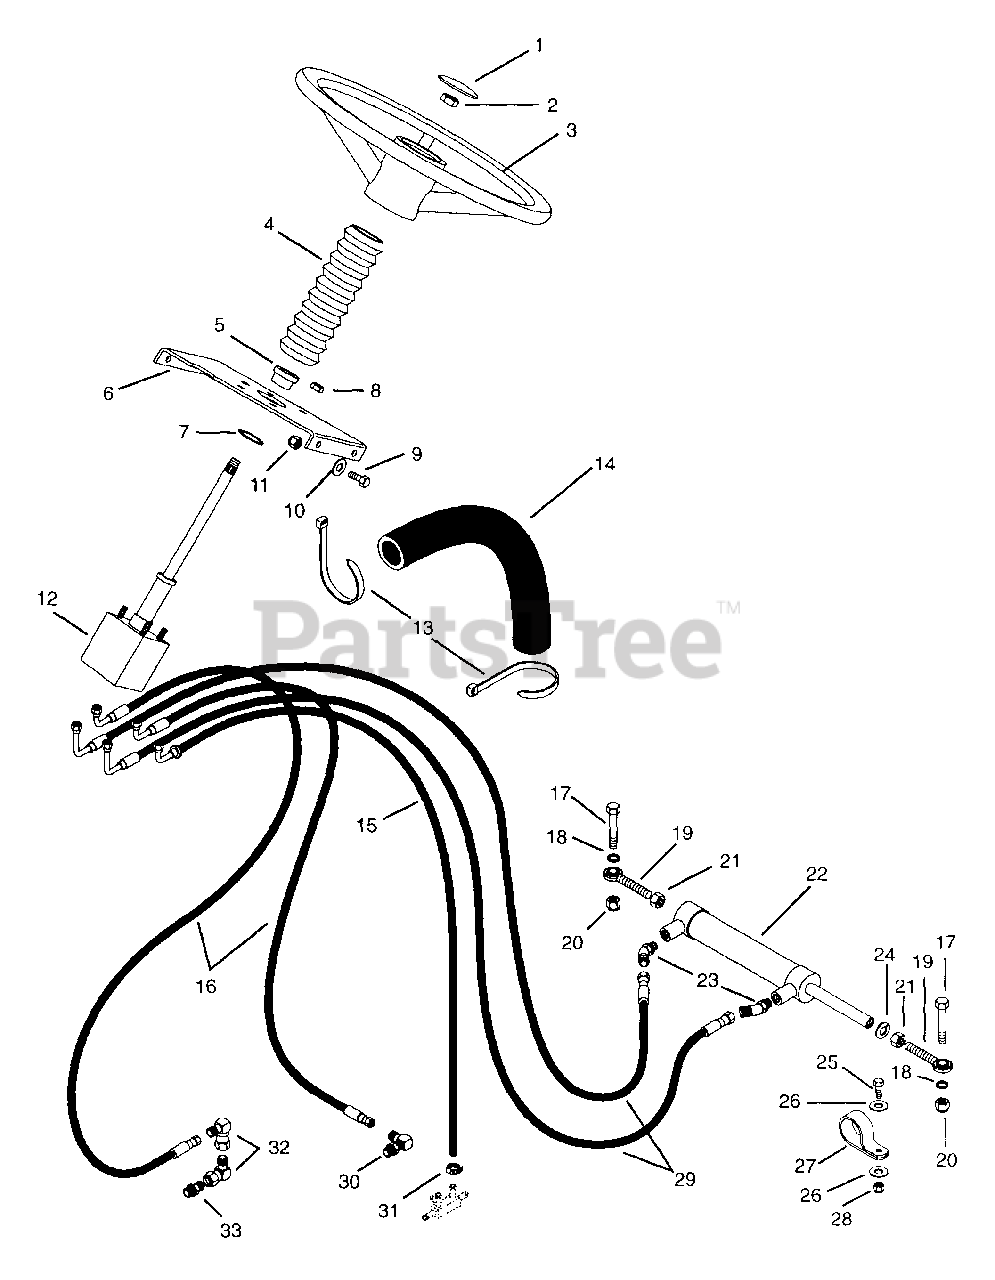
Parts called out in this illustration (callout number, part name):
1	Steering Wheel Cap
2	Nut-Jam .625-11
3	Steering Wheel
4	Steering Column Boot
5	Bushing-Flange .762 x 1.0 x .580 x 1.48
6	Bracket, Steering Pump
7	Ring-Retaining-External 1.31 x .05
8	Nut-Locking-Nylon .312-24 Grade 2
9	Bolt-Hex .31-18 x .75 Grade 5
10	Washer-Flat-Steel .344 x .688 x .065
11	Nut-Locking-Nylon .312-18 Grade 2
12	Power Steering Unit
13	Tie Wrap, Black
14	Sleeve 12"
15	Assembly, Hydraulic Hose
16	Assembly, Hydraulic Hose
17	Bolt-Hex .50-13 x 2.00 Grade 5
18	Bushing
19	Assembly, Rod End (Right Hand)
20	Nut-Locking-Nylon .50-13 Grade 5
21	Nut-Jam .50-20 Grade 2
22	Cylinder, Steering
23	Adapter
24	Washer-Lock .50 Reg.
25	Bolt-Hex .38-16 x 1.00 Grade 5
26	Washer-Flat-Steel .406 x .812 x .065
27	Clamp, Nylon
28	Nut-Locking-Nylon .375-16 Grade 2
29	Hydraulic Hose Assembly
30	Adapter
31	Hose Clamp
32	Adapter
33	Adapter-Pipe .56-18 "O" Ring To .56-18
